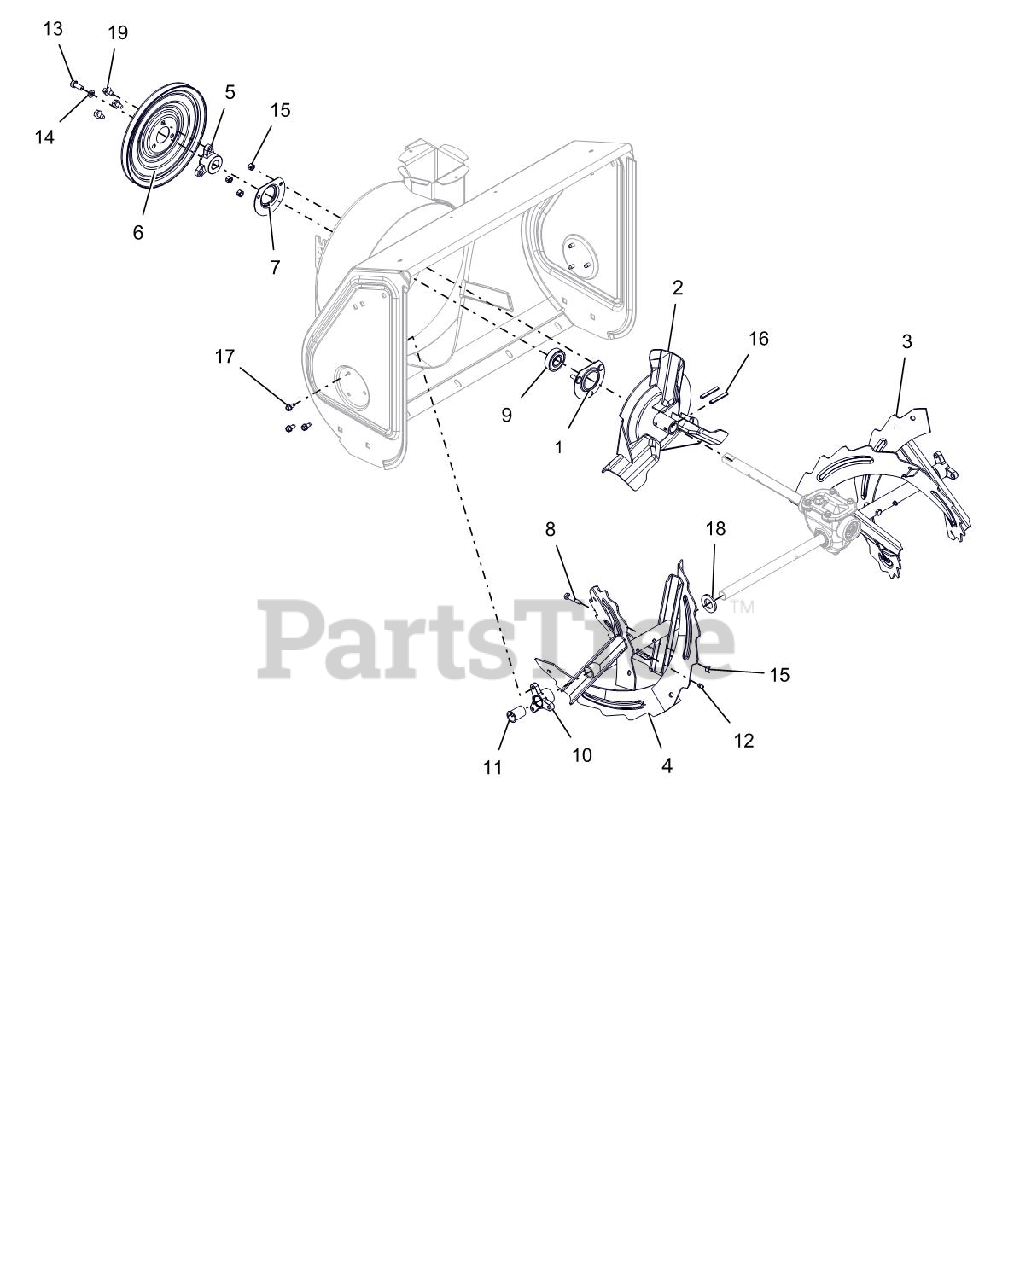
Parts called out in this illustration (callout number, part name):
1	BEARING FLANGE
2	IMPELLER, COMPACT 12" 3-BLADE
3	RAKE, 24" LH, BLK SERR W/ZERK
4	RAKE, 24" RH, BLK SERR W/ZERK
5	PULLEY HUB, BOLT-ON D-BORE .75
6	PULLEY,SPIN FORM SINGLE GROOVE
7	BEARING FLANGE
8	SHEAR BOLT WITH NUT
9	BRG-BALL .750X1.750X.50
10	BUSHING, RAKE SHAFT .75"
11	BSHG-FLG SPLIT NYLINER .75"ID
12	ZERK,FITTING .25X.125 DRIVE IN
13	BLT-HEX .31-24X.75 YWZC GR5
14	WSHR-LK .312X.097 HVY YWZC
15	@NUT-LK-CTR .25-20 YWZC
16	PIN-ROLL .250X1.75
17	SCR-TAP .25-20X.50 HWH TR YWZ
18	@WSHR-FL-STL.812X1.50X.135YWZC
19	@SCR-TAP .31-18X.50 HWH TR YWZ
